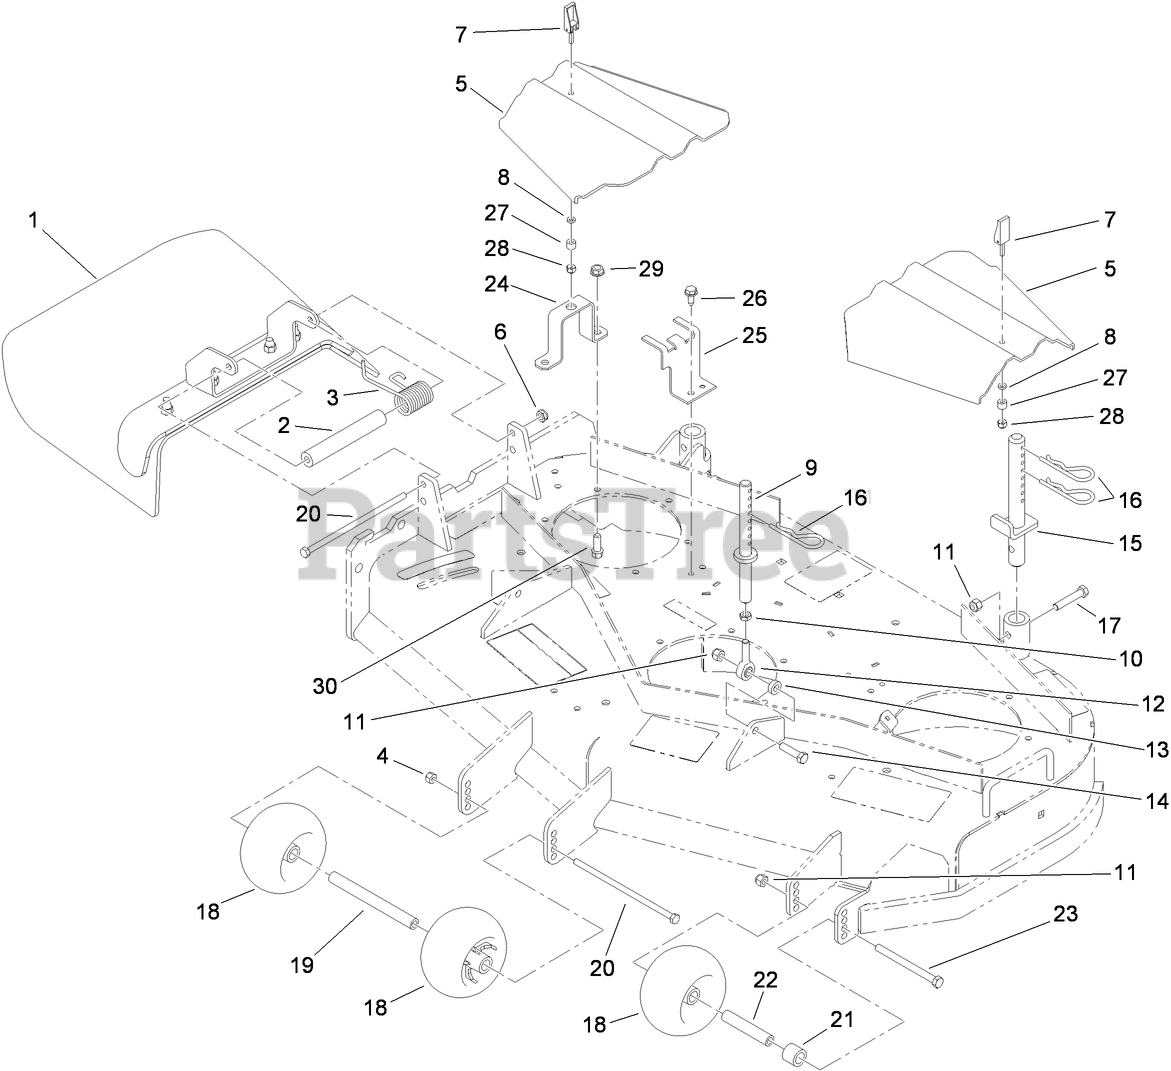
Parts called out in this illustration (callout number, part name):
1	DEFLECTOR ASM
2	SPACER
3	SPRING-TORSION
4	NUT-LOCK, NI
5	COVER-BELT
6	NUT-LOCK, NI
7	HANDLE-LATCH, SWELL
8	WASHER
9	FRONT PIN ASM
10	NUT-HJ
11	NUT-LOCK, NI
12	BALLJOINT
13	SPACER
14	SCREW-HH
15	REAR PIN ASM
16	PIN-HAIR
17	SCREW-HH
18	ROLLER-SCALP, ANTI
19	SPACER-WHEEL
20	SCREW-HH
21	TUBE-SPACER
22	TUBE-SPANNER
23	SCREW-HH
24	BRACKET-COVER
25	BRACKET-COVER
26	SCREW-HWHTF
27	BUSHING-LATCH, SWELL
28	NUT-LOCK, HH
29	NUT-HF, NI
30	SCREW-HWH
